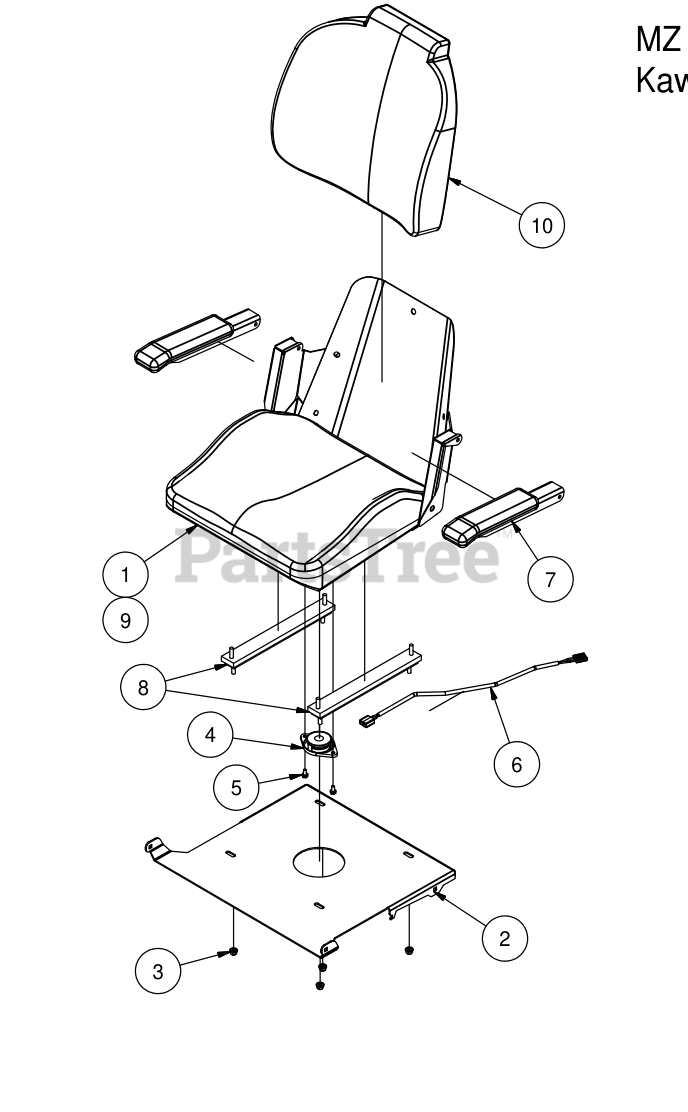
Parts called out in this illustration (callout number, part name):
1	2017 Zt Seat
2	Seat Plate 2016
3	5/16" Nylon Flange Nut
4	Seat Safety Switch
5	1/4-20x1/2 HWH Bolt Slot
6	Seat Switch Adapter
8	Seat Rail Pair
9	Seat Bottom Cushion
10	Seat Back Cushion
